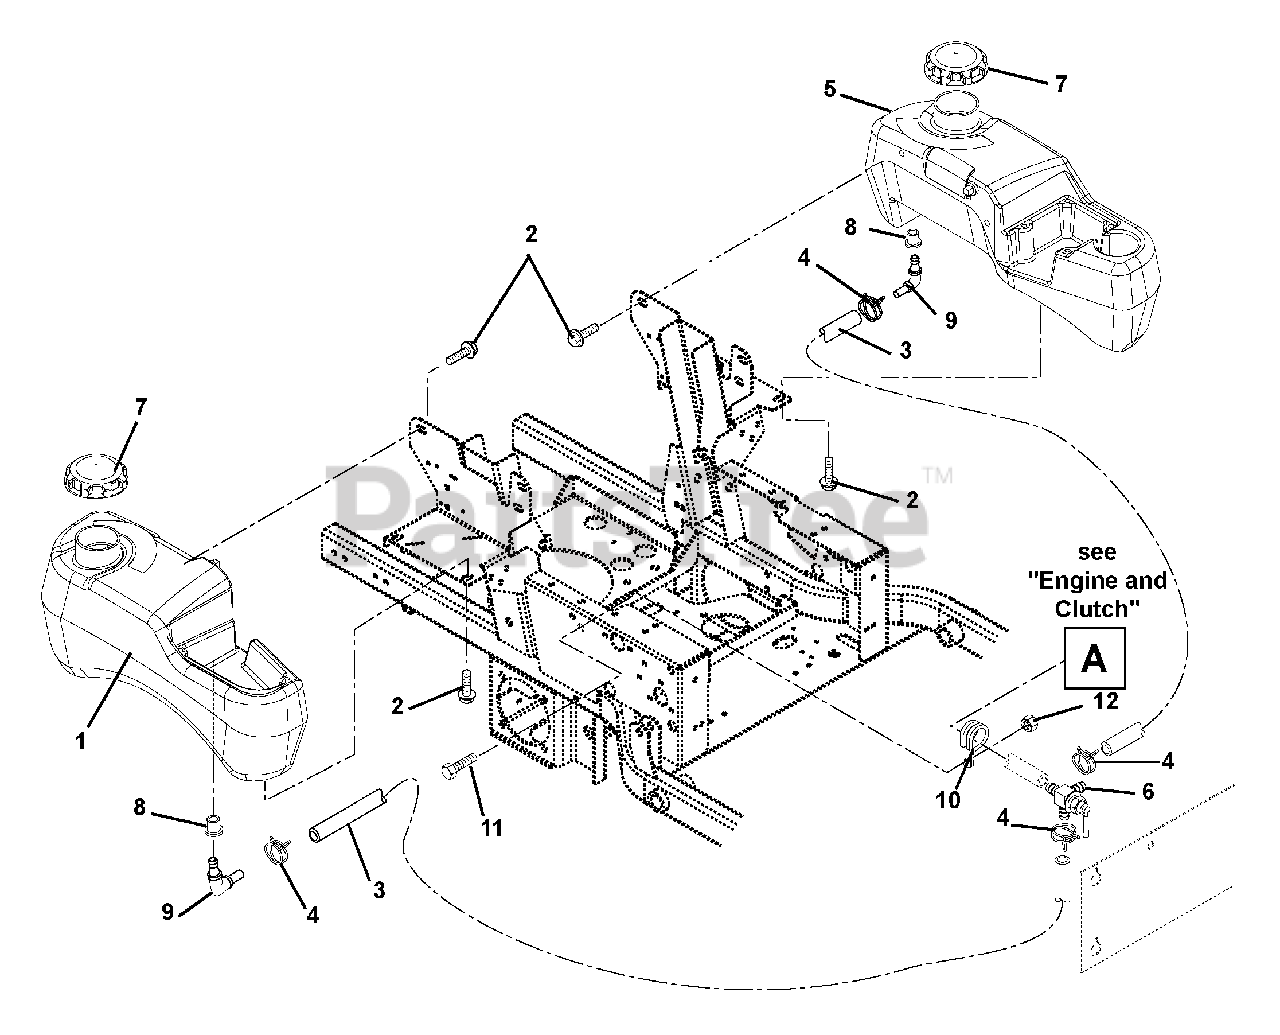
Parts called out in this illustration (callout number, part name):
1	Tank, Gas - Right Hand
2	Bolt, SEMS .31-18 x .62
3	Gas Line, Bulk .25" ID
4	Hose, Clamp
5	Tank, Left Hand Fuel (EYE-Q) 100 Series
6	Valve, Fuel
7	Cap, Gas
8	Grommet, Black (Will not replace orange)
8	Grommet, Orange (Will not replace black)
9	Fuel Tank Fitting
10	Clamp, Cushioned Steel (992054, 055, 081, 082, 096, 097)
11	Bolt, Hex .38-16 x 1.00 Grade 5 (992054, 055, 081, 082, 096, 097)
12	Nut, Locking Top Flange .38-16 (992054, 055, 081, 082, 096, 097)
